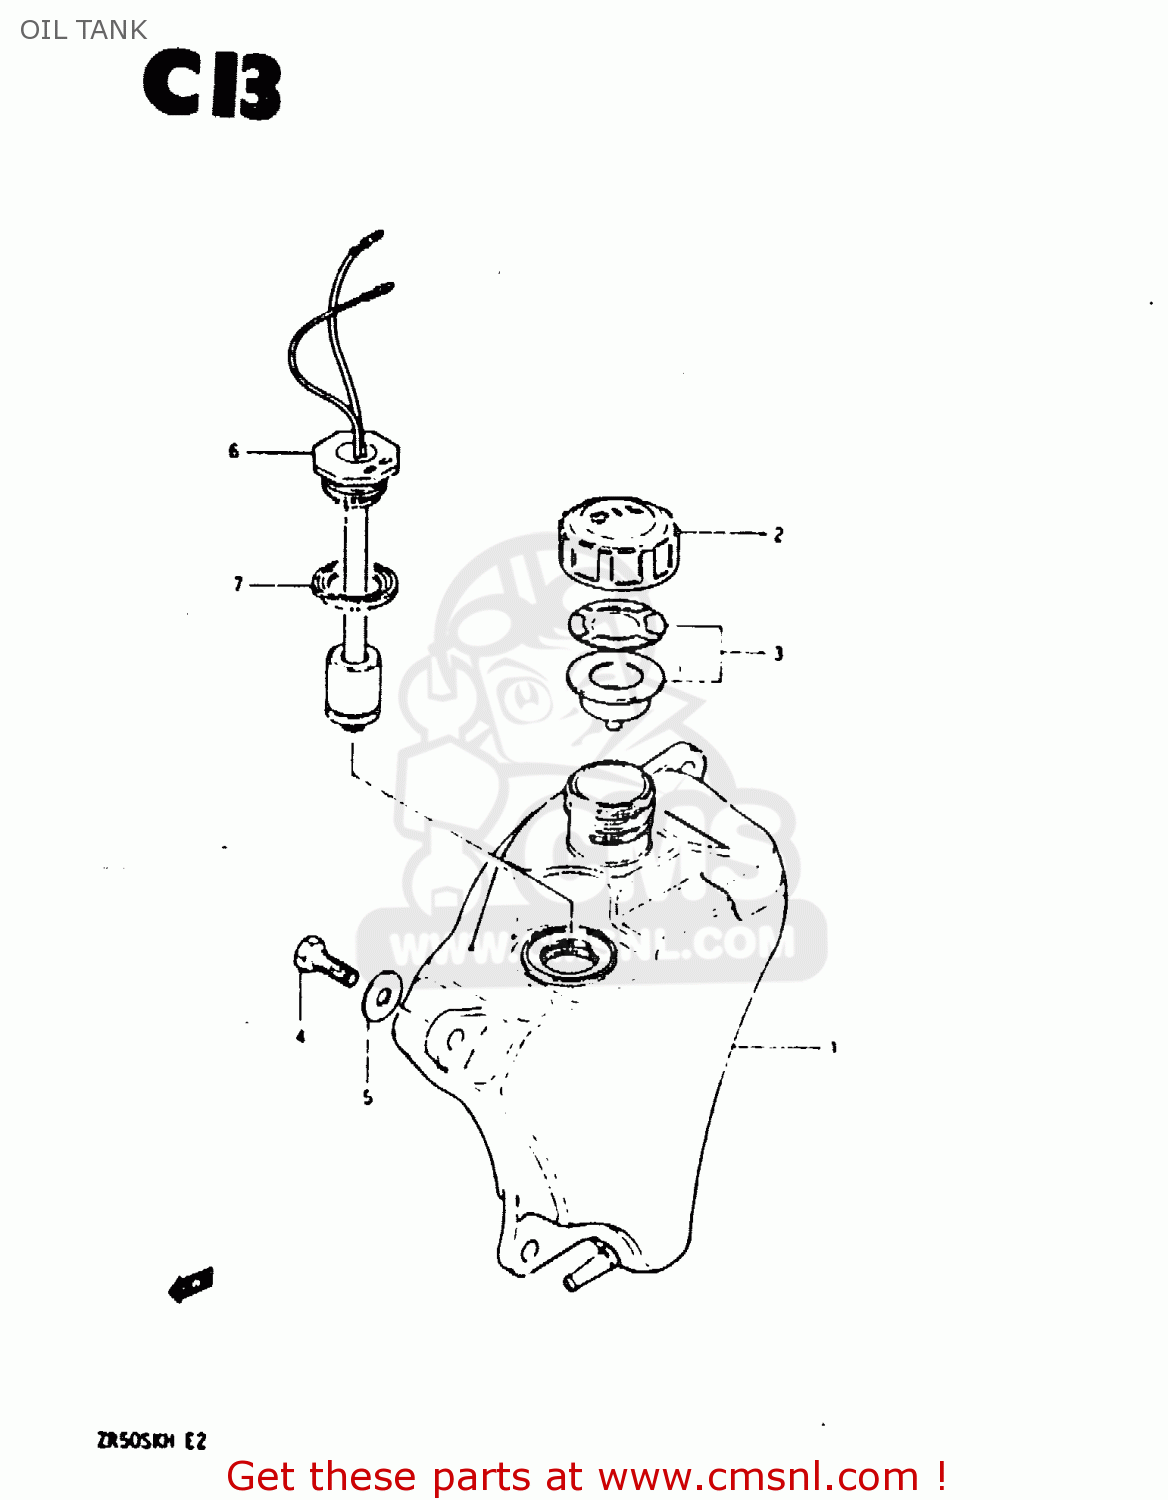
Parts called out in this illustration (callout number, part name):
1	TANK, OIL
2	CAP,OIL TANK
3	GASKET SET (NAS)
4	BOLT
5	WASHER
6	SWITCH ASSY, OIL LEVEL
7	GASKET (NAS)
